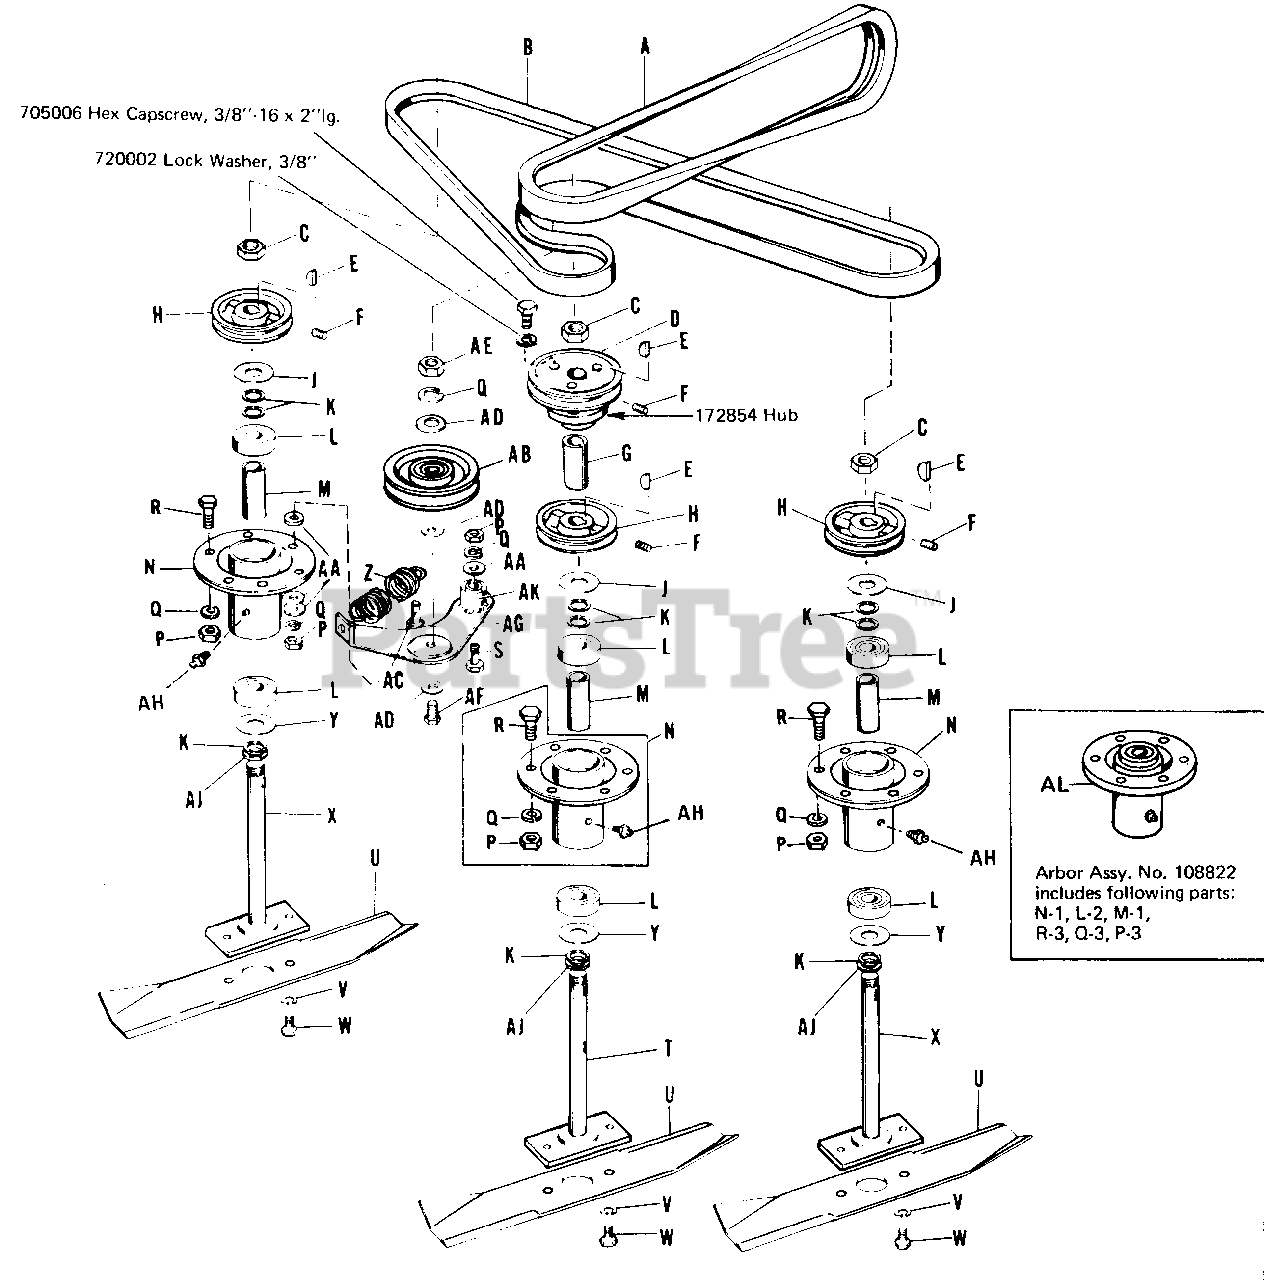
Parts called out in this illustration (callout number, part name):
B	Belt, "V" (Mower Spindle Drive)
C	Hex, Jam Lock Nut, 3/4"-16
D	Cross drive Pulley
E	Key, Woodruff, 61
F	Set Screw, 5/16"-18 x 3/8"
J	Backing Ring
N	Arbor Tube Assembly
P	Full Hex, Nut, 3/8"-16
Q	Lock Washer, 3/8"
R	Hex Cap Screw, 3/8"-16 x 3/4" lg.
S	Hex, Cap Screw 3/8"-16 x 1-3/4" lg.
T	Arbor Drive Assembly
U	Knife Blade
V	Lock Washer, 3/8"
W	Hex. Hd. Capscrew, 3/8"-16 x 5/8"
X	Arbor Assembly
AA	Plain Washer, 5/16"
AB	Idler Pulley
AD	Plain Washer, 5/16"
AE	Full Lock Hex. Nut, 3/8"-16
AG	Idler Lever Assembly
AH	Grease Fitting
AL	Arbor Assembly with Bearings and Hardware
